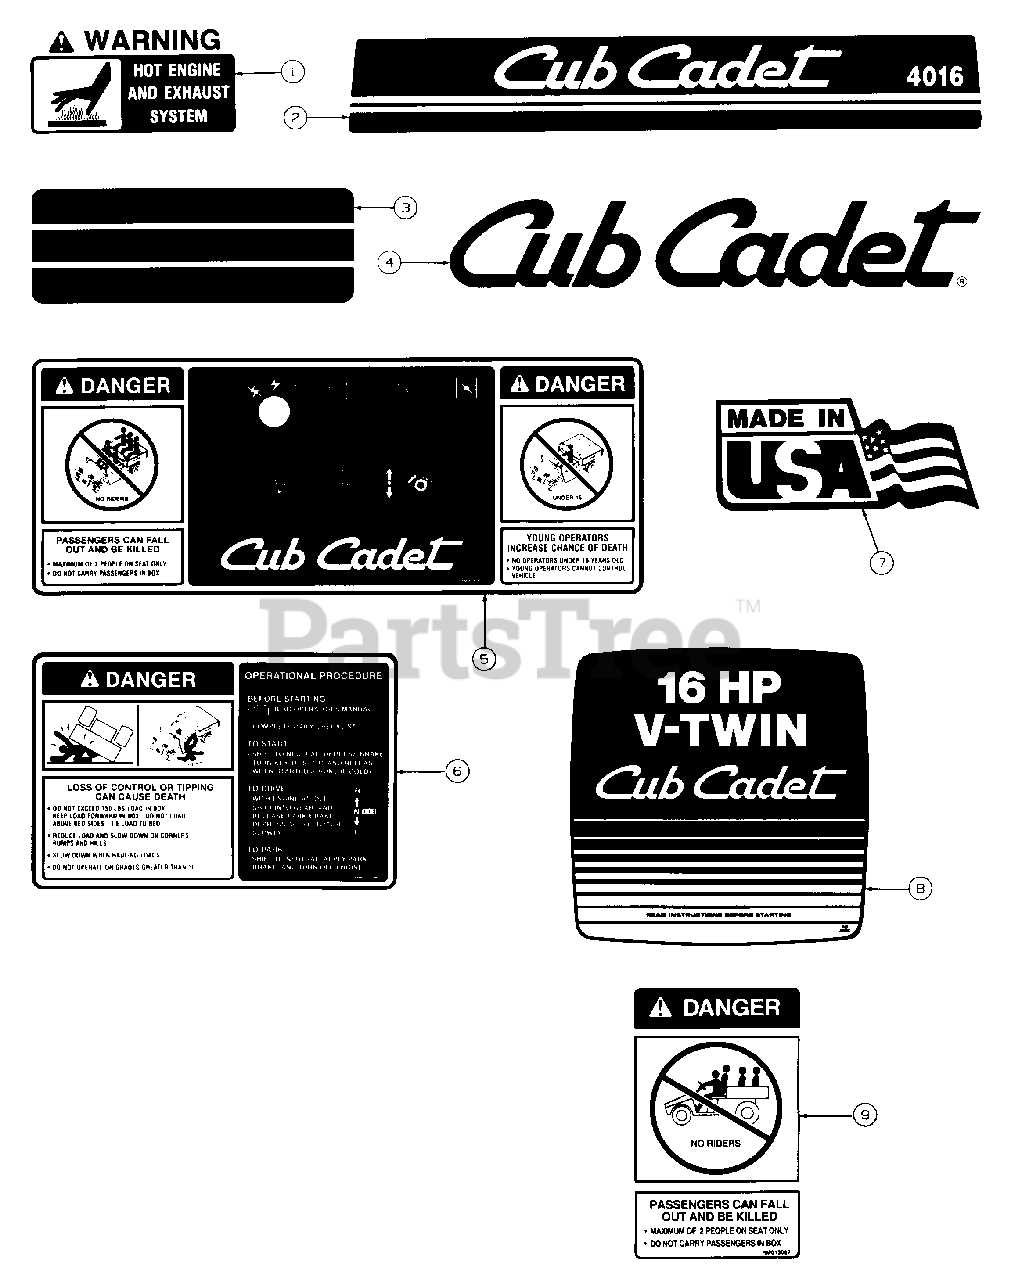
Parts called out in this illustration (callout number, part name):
1	Graphic, Warning
2	Graphic, Front Hood
3	Graphic, Reflector
4	Graphic, Logo
5	Graphic, Dashboard
6	Graphic, Operation
7	Graphic, Made in the USA
8	Graphic, 16 HP V-TWIN
9	Graphic, NO Riders
